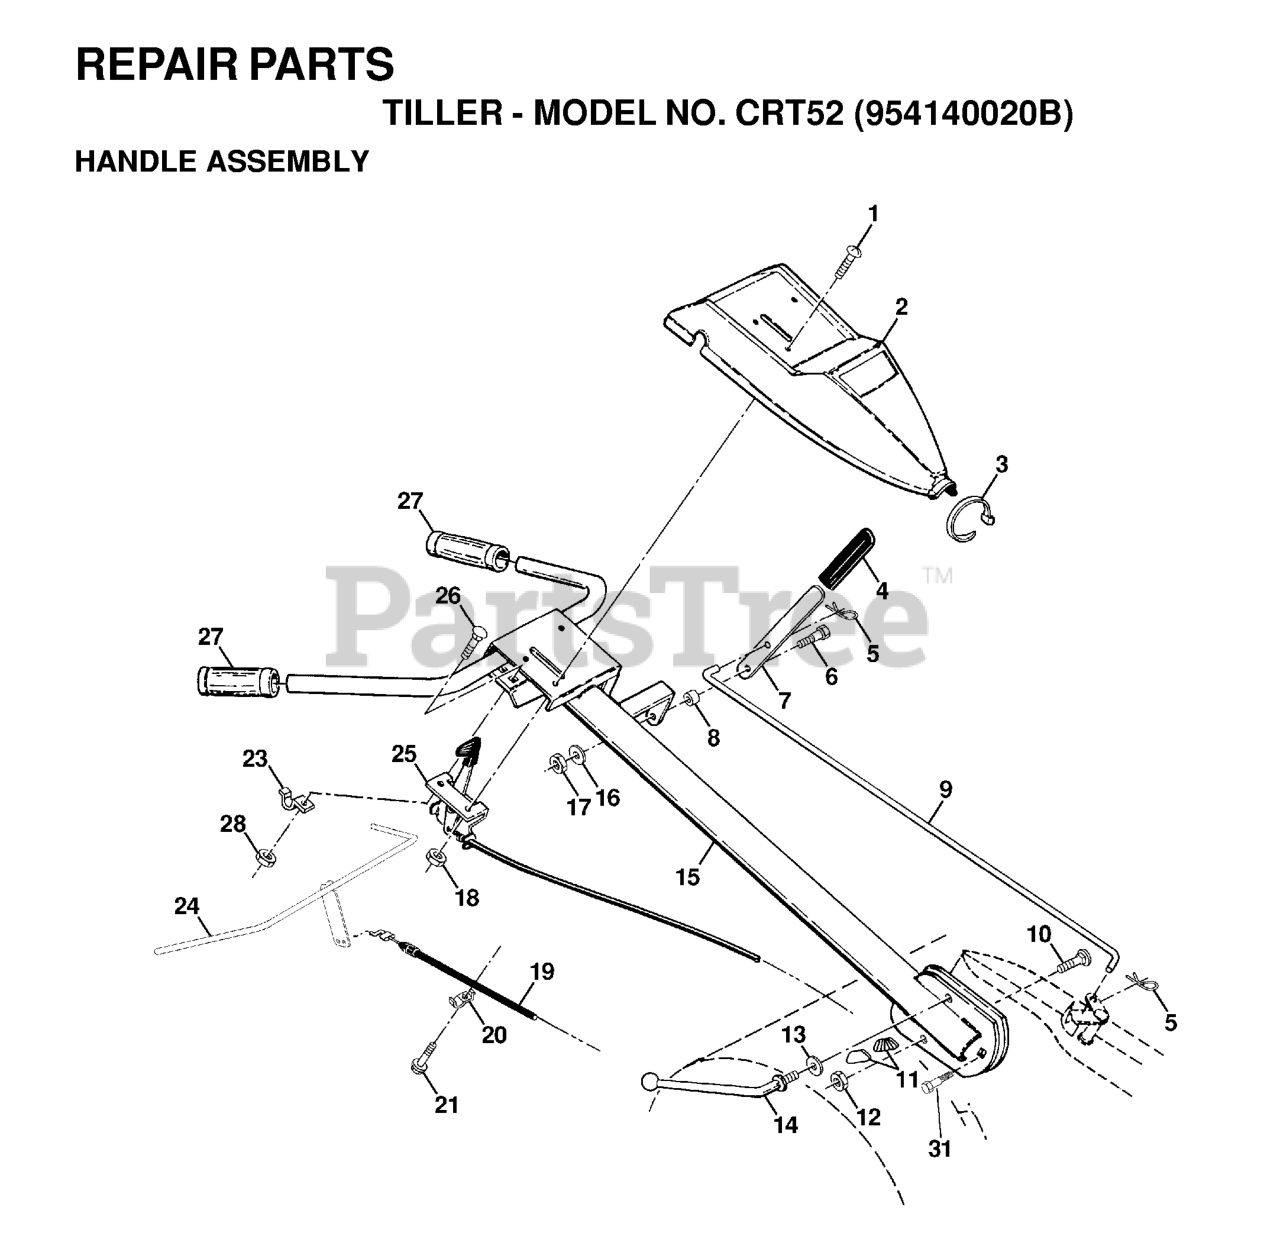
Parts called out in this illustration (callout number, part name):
2	MUFFLER.ASM.TWIN.MNTG.BRACKET
9	KEEPER.BELT.ENG.4.25"2.BLT.431
11	CLUTCH.OGURA.5.0PD.GT1.5A-EH01
12	PULLEY ENGINE
15	Tanks
18	CAP ASSY FUEL 3" GRAY
18	FUEL CAP
20	THROTTLE.KOHL.PRO.#88PAD_46"
21	SCREW.#10 X 0.750.BOS
28	LINE.FUEL.64"REAR.EMIS
29	KIT.SPARK ARRESTOR 794945 B&S
37	HOSE CLAMP
42	WASHER 7/16 LOCK
45	NUT
62	SHIELD.HEAT.MUFFLER
69	GASKET.EXHAUST.KOHL.CV18-CV26
70	PIPE.EXHAUST.LH.CV18/20
71	PIPE.EXHAUST.RH.CV18/20
81	TUBE, DRAIN OIL ASM.
82	VALUE.OIL.DRAIN
85	BOLT.HEX.7/16-20X3.GR5.YELLOW
86	NUT.HEX.FLANGE.TOPLOCK
90	SCREW 3/8-16X1
91	BUSHING.1.375OD
92	SCREW 3/8-16X1
102	SCREW
109	CANNISTER, CARBON
111	RP PURGE LINE
113	VALVE.SLANT.CARTRDG.90 DEG.TEX
116	KNOB - SHIFT
117	VALVE FUEL RESERVE
